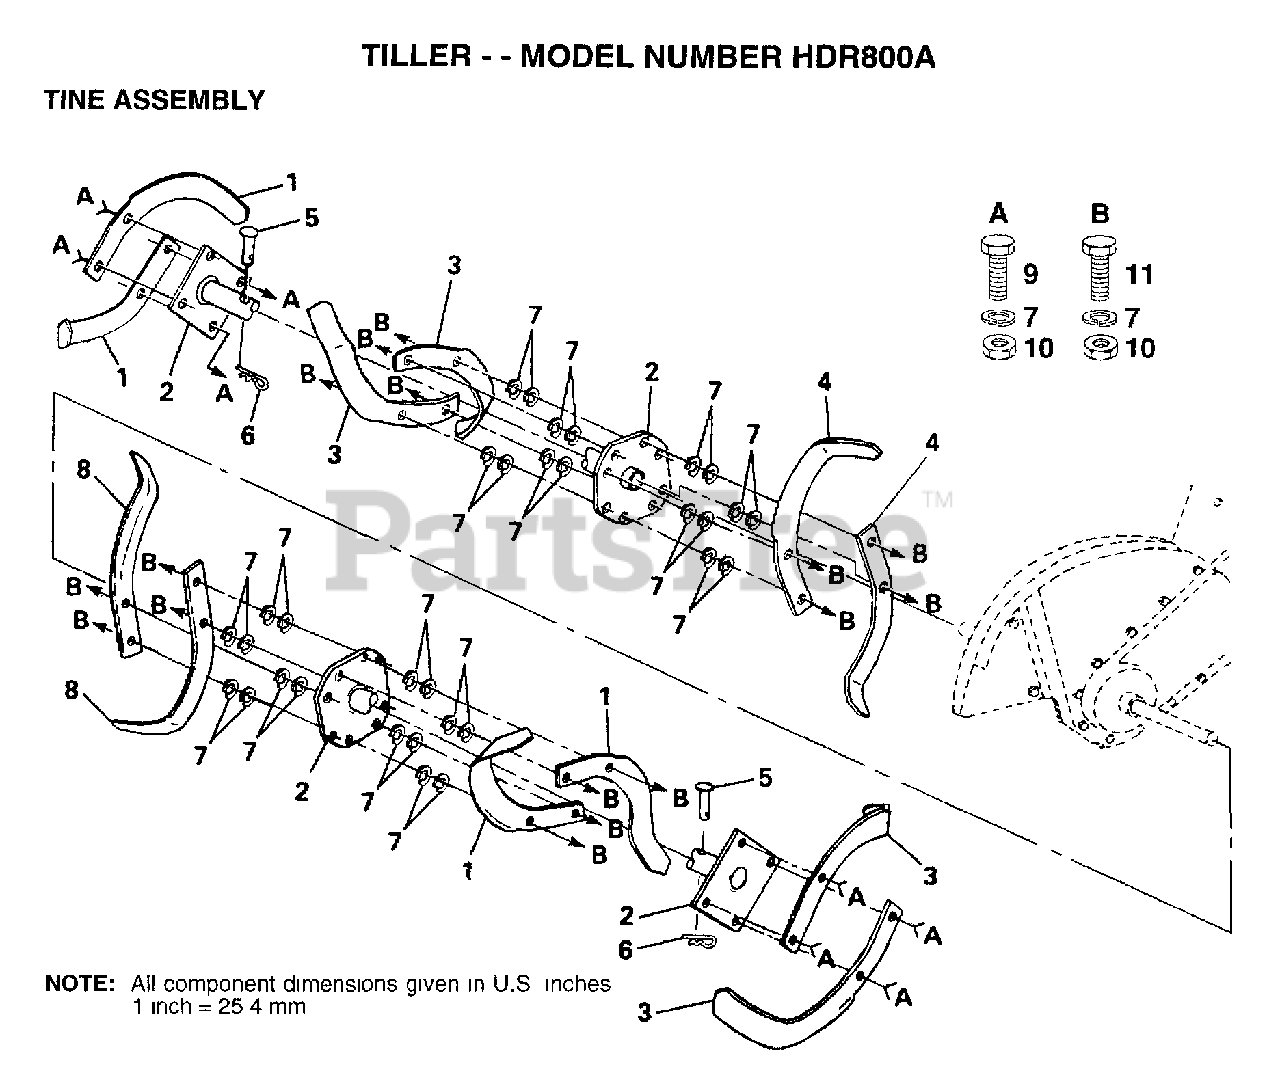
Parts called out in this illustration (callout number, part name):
2	TINE ASSY CRT
4	TINE.LH.CRT
5	RIVET.PAN HD.1.75
6	RETAINER.SPRING
7	LOCKWASHER
8	TINE RH CRT
9	BOLT
11	BOLT.3/8-24X1-1/2
